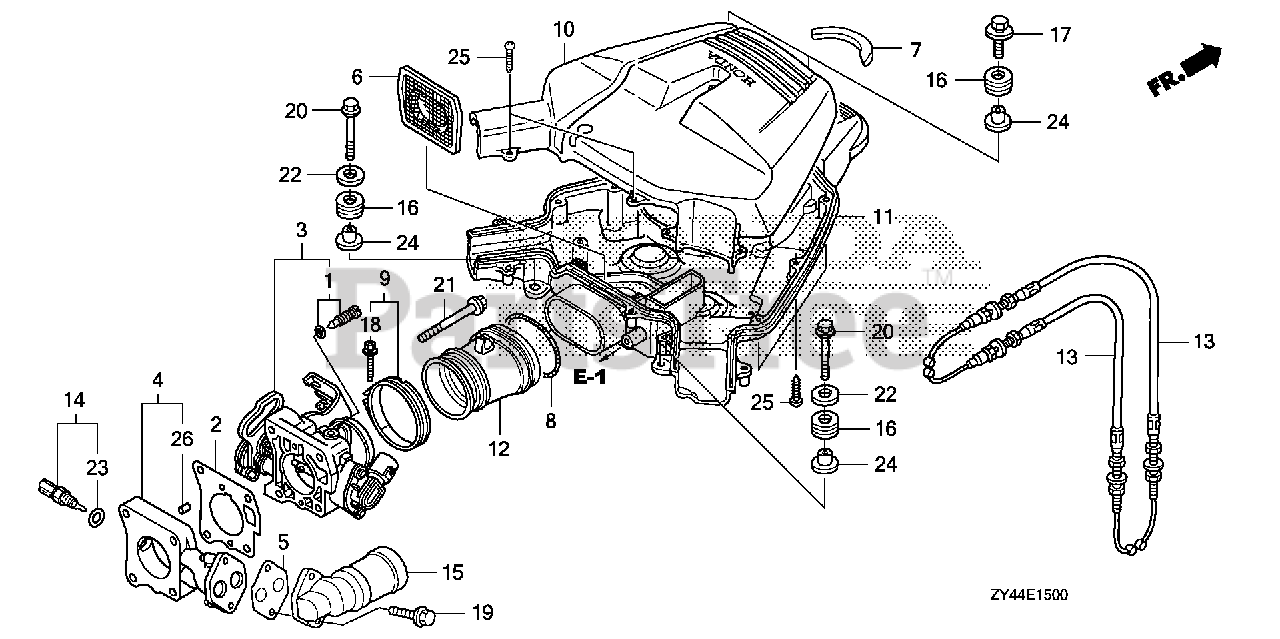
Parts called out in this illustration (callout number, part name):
2	GASKET, THROTTLE BODY
3	BODY ASSY., THROTTLE
4	SPACER, THROTTLE BODY
5	GASKET, EAC VALVE
6	TRAP, FLAME
7	RUBBER, SEAL MUFFLER
8	SPRING, AIR FLOW TUBE
9	BAND, AIR FLOW
10	CASE A, MUFFLER
11	CASE B, MUFFLER
12	GROMMET, MUFFLER
13	CABLE, THROTTLE
14	SENSOR ASSY., AIR TEMPERATURE
15	VALVE ASSY., EAC
16	GROMMET, CASE (LOWER)
17	BOLT-WASHER (6X25)
18	BOLT-WASHER (5X30)
19	BOLT, FLANGE (6X22)
20	BOLT, FLANGE (6X60)
21	BOLT, FLANGE (8X65)
22	WASHER, PLAIN (6MM)
24	COLLAR, MODULE IGNITION CONTROL CASE (CDI)
25	SCREW, TAPPING (5X20)
26	PIN, DOWEL (6X10)
